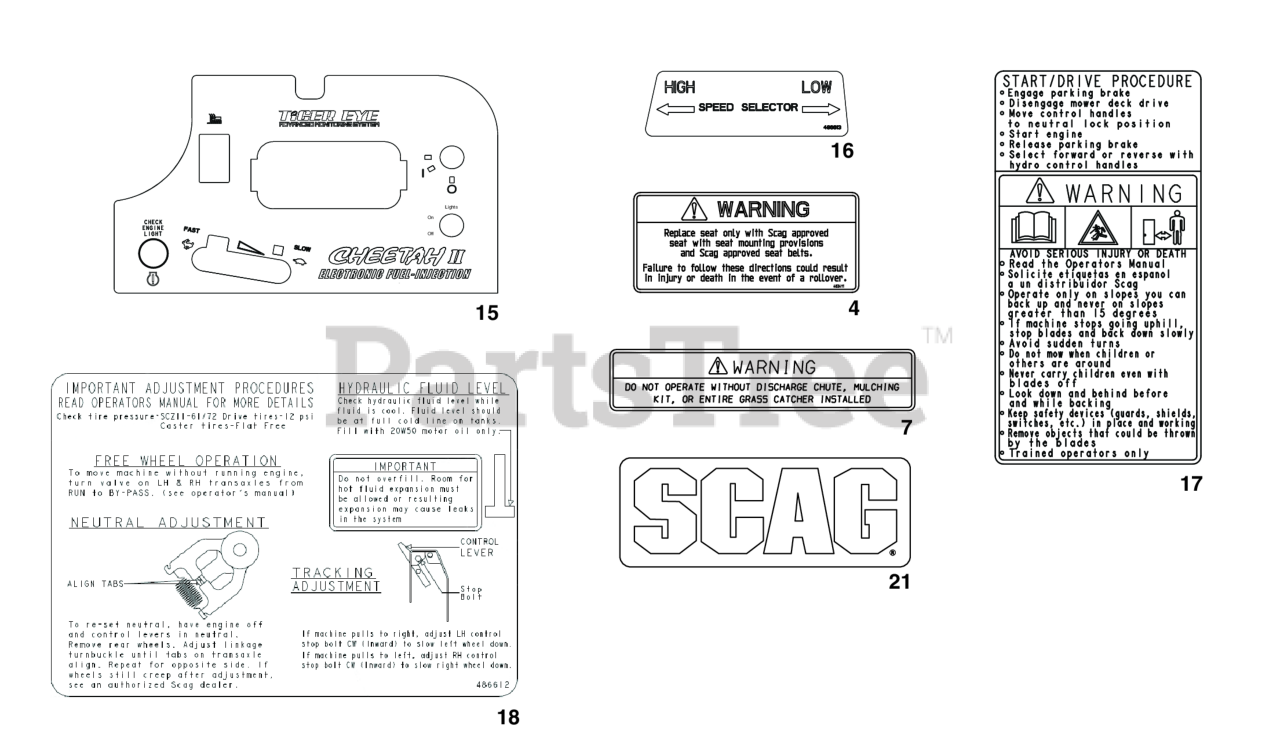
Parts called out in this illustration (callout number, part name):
4	Decal, Seat Replacement
7	Decal, Warning-Discharge
15	Decal, Instrument Panel - SCZII - EFI
16	Decal, Speed Control
17	Decal, Start / Drive
18	Decal, Adjustments - SCZII
21	Decal, Scag - Fuel Tank
